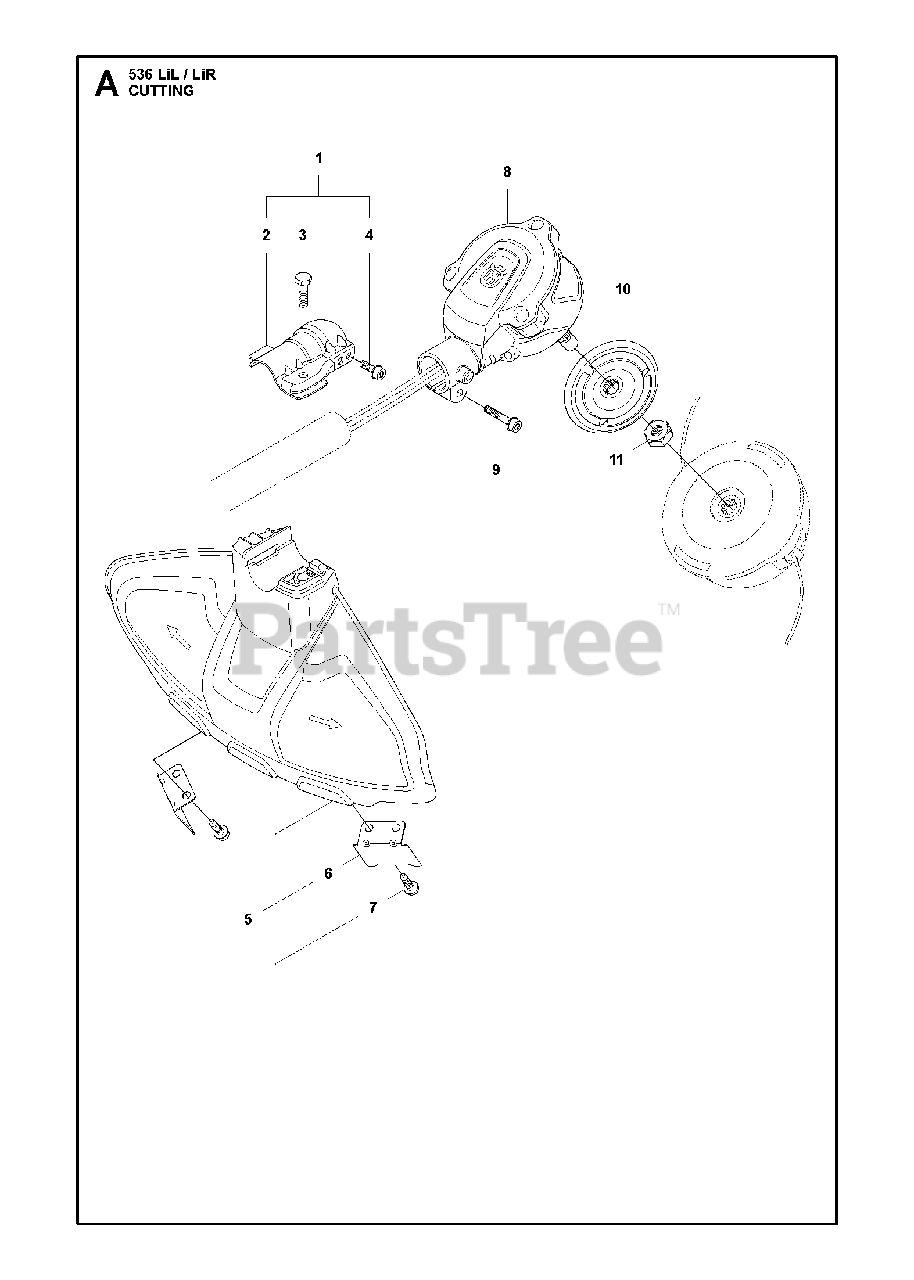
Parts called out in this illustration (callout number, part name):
1	CLAMP
2	RP BRACKET TRIMMER GUARD
3	SCREW
4	SCREW
5	TRIMMER SHIELD ASSY
6	LINE LIMITER
7	SCREW
8	MOTOR ASSY
10	DRIVER ASSY
